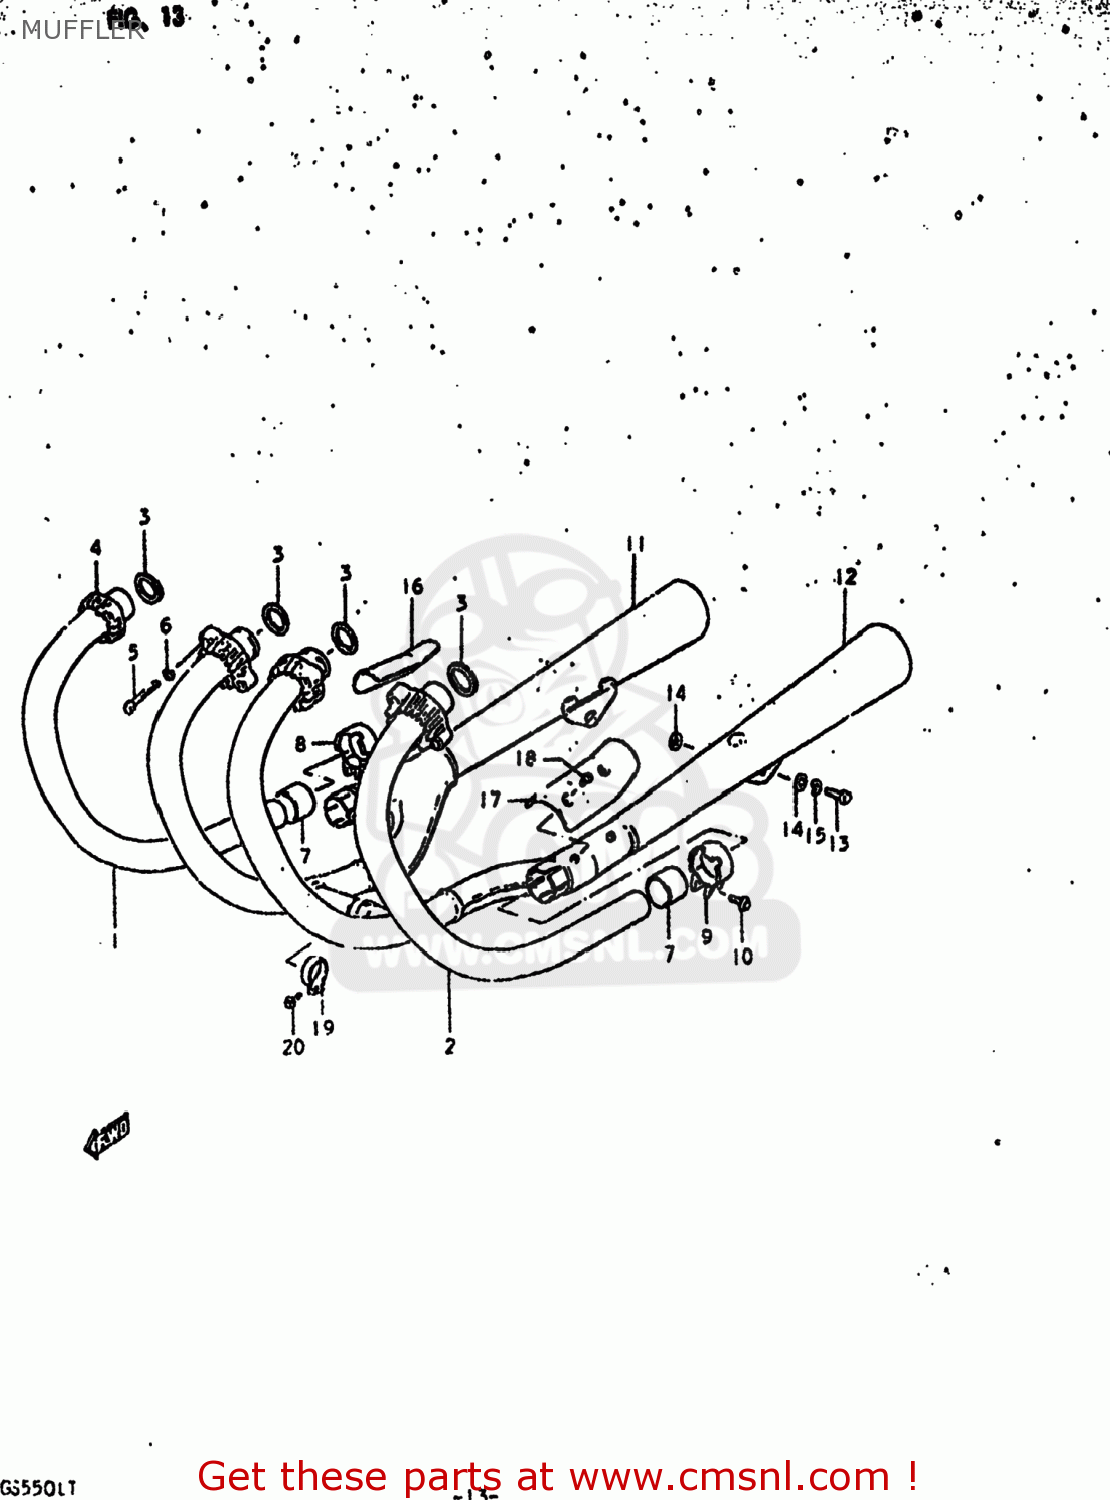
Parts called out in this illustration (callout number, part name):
1	PIPE,EXHAUST,RIGHT
2	PIPE,EXHAUST,LEFT
3	GASKET,EXHAUST PIPE (NAS)
4	CLAMP,EXHAUST PIPE
5	BOLT
6	LOCK WASHER
7	CONNECTOR,MUFFLER
8	CLAMP,MUFFLER CONNECTOR,R
9	CLAMP,MUFFLER CONNECTOR,L
10	BOLT
11	BODY,MUFFLER
12	BODY,MUFFLER
13	BOLT 10X30
14	WASHER
15	LOCK WASHER
16	COVER,MUFFLER,RIGHT
17	COVER,MUFFLER,LEFT
18	SCREW
19	CLAMP,EXHAUST COUPLER
20	BOLT,REAR
